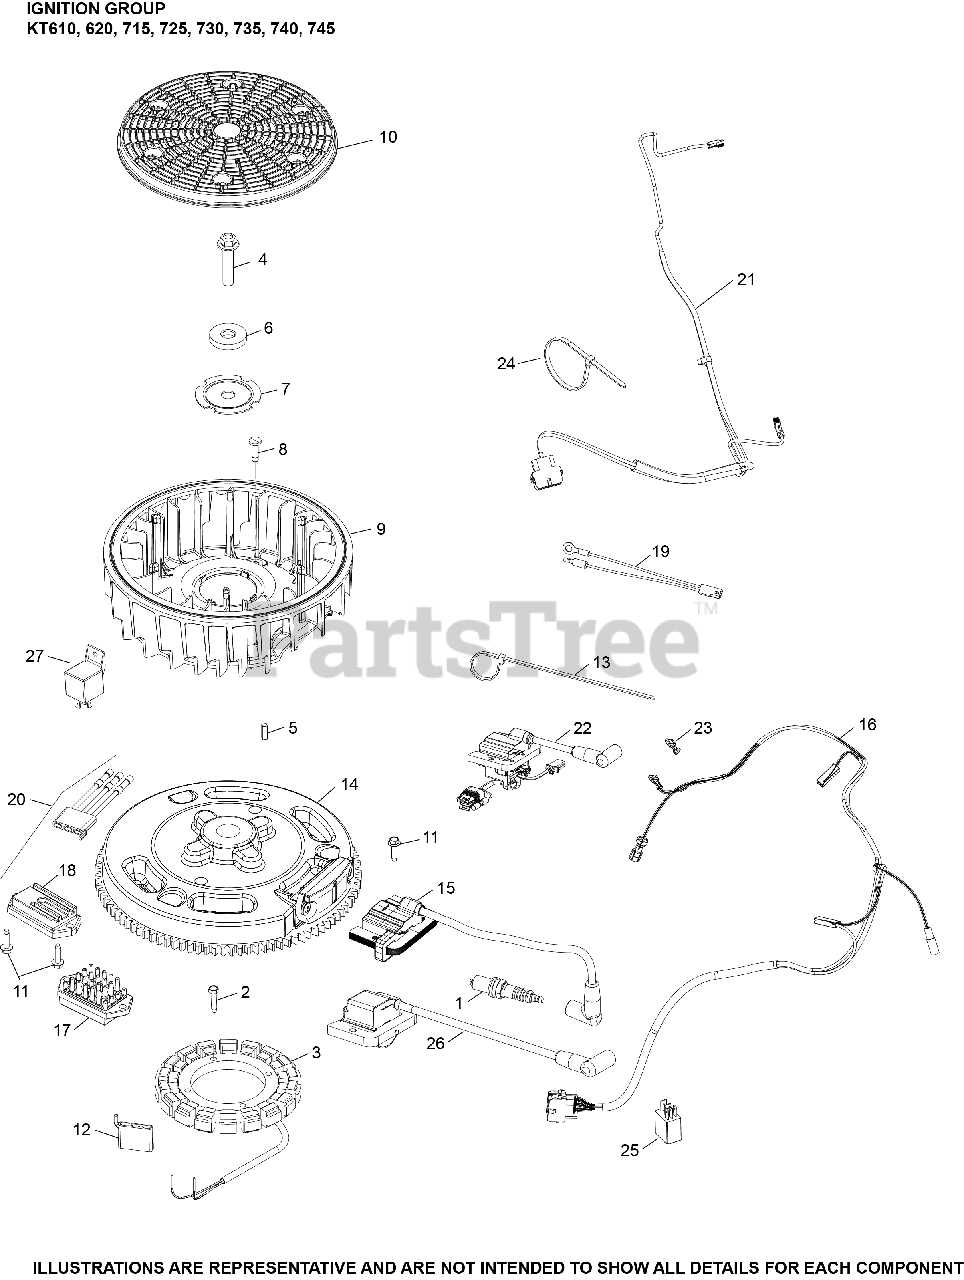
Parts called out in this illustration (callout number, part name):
1	PLUG, SPARK
2	SCREW, THREAD FORMING
3	KIT, 15 / 20 AMP STATOR
4	SCREW, HEX FLANGE
5	KEY, SQUARE
6	WASHER, FLAT
7	PLATE, FAN MOUNTING
8	RETAINER, FLYWHEEL FAN
10	SCREEN, GRASS
11	SCREW, THREAD FORMING - USE 25 086 473-S
12	CONNECTOR
14	FLYWHEEL ASSEMBLY
15	MODULE, IGNITION
16	HARNESS , WIRING ASSEMBLY
18	REGULATOR/RECTIFIER 12/15A HALF-WAVE STD
